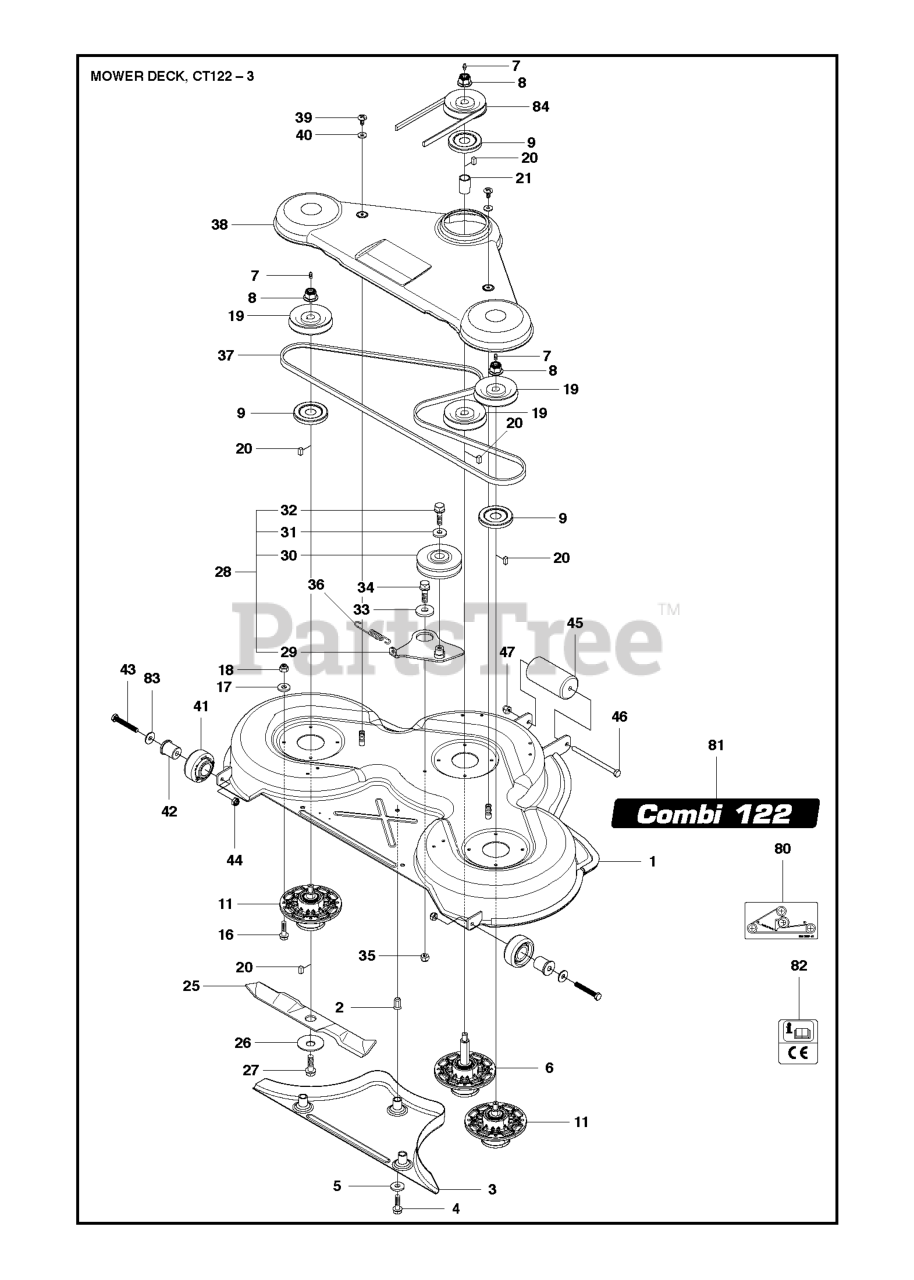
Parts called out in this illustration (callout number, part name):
4	SCREW
5	WASHER BRB 8.4X17
7	GREASE NIPPLE
17	WASHER BRB 8.4X17
18	LOCKNUT M8
29	BELT TENSIONING ARM
33	WASHER
35	LOCKNUT M8
44	NUT
45	ROLLER
